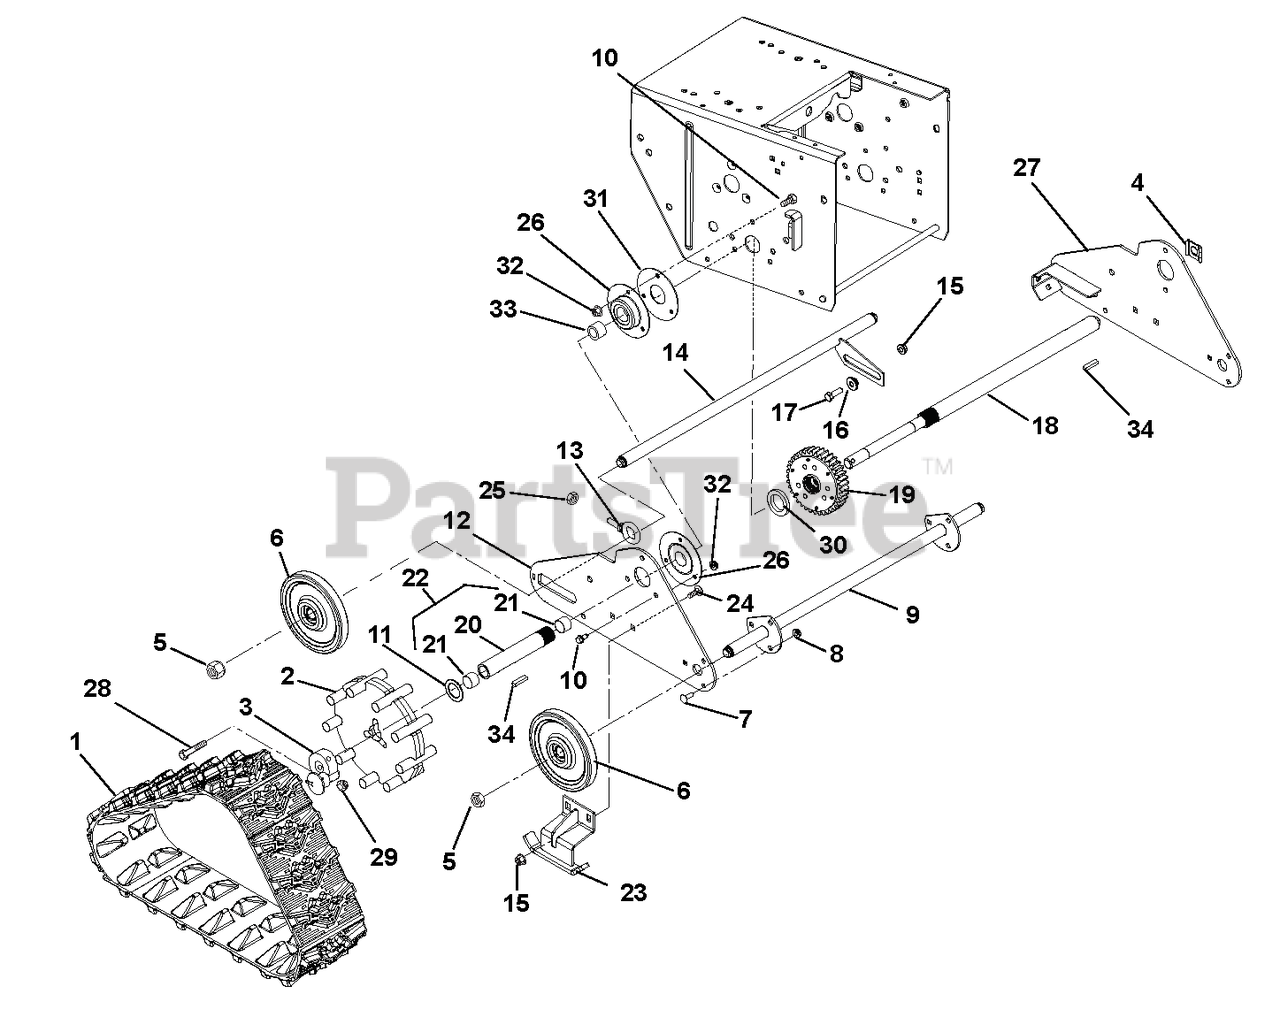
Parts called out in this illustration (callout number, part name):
1	TRACK, RUBBER
2	WHEEL, DRIVE-TRACK
3	HUB, LOCKOUT-ASSEMBLY
4	CLIP, SNAP .625 DIA
5	@NUT-LK-NYL .625-18 YWZC
6	WHEEL, BOGIE - SINGLE BEARING
7	@BLT-RDHDSQNK .25-20X.75 G5YZ
8	@NUT-LK-TOP-FLG .25-20 YWZC
9	AXLE, FRONT - PRO
10	@BLT-HEX .25-20X.75 GR5 YWZC
11	WSHR-FL-STL 1.010X1.505X.062YZ
12	SIDE PLATE, RH-TRACK
13	BLT-EYE .375-16X.880 YWZC
14	AXLE, REAR - PRO TRACK
15	@NUT-LK-TOP-FLG .31-18 YWZC
16	BSHG, FLG .325X.499X.26X.88
17	@BLT-HEX .31-18X1.00 GR5 YWZC
18	AXLE, LONG-TRACK DIFFERENTIAL
19	DIFFERENTIAL, AXLE LOCK
20	AXLE, SHORT-TRACK DIFFERENTIAL
21	BSHG-SLV .706X.764X.75 BRZ
22	AXLE, SHORT-TRACK W/BUSHINGS
23	RUNNER, GUIDE-TRACK
24	@BLT-RDHDSQNK .31-18X.75 G5YZ
25	NUT-LK-CTR-FLG .38-16 YWZC
26	BRG-FLG 1.003/1.000 3 BOLT
27	SIDE PLATE, LH-TRACK
28	@BLT-HEX .25-20X2.00 GR5 YWZC
29	@NUT-LK-CTR .25-20 YWZC
30	WSHR-FL-NY 1.38X2.00X.25
31	PLATE, BEARING SPACER
32	@NUT-LK-TOP-FLG .25-20 YWZC
33	BSHG-SLV, 1.012X1.125X1.00
34	KEY-RECT .25X.188X1.00
